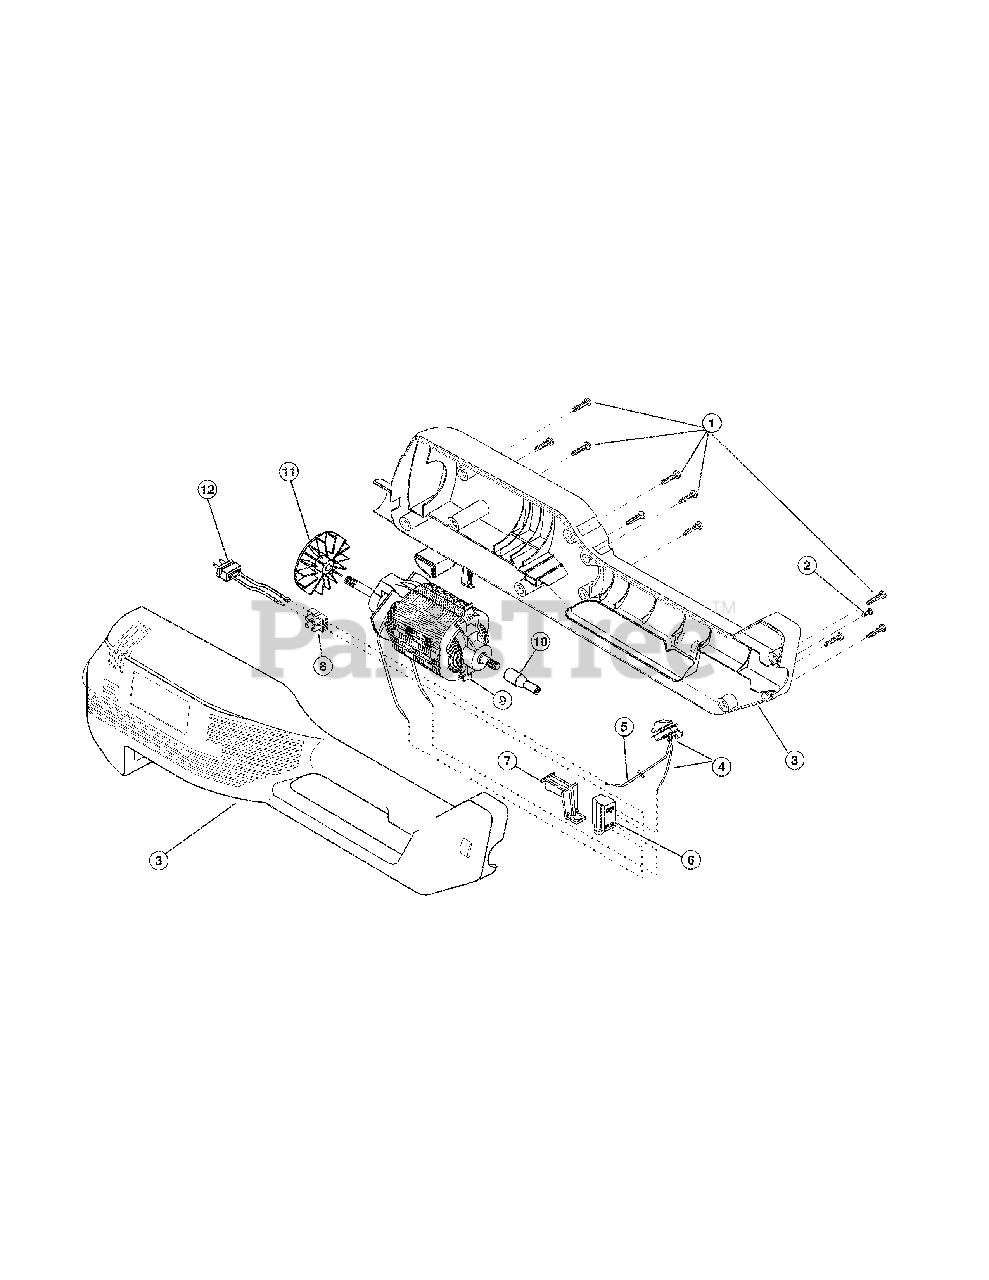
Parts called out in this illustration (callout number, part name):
1	Screw, Housing Set (Qty. 11)
2	Anti-Rotation Screw
3	Motor Housing Assembly
4	Two-Speed Switch Assembly
5	Lead Wires
7	Trigger
8	Terminal Block
9	Motor Assembly (includes 11 & 12)
11	Cooling Fan
12	Recessed Plug Assembly
